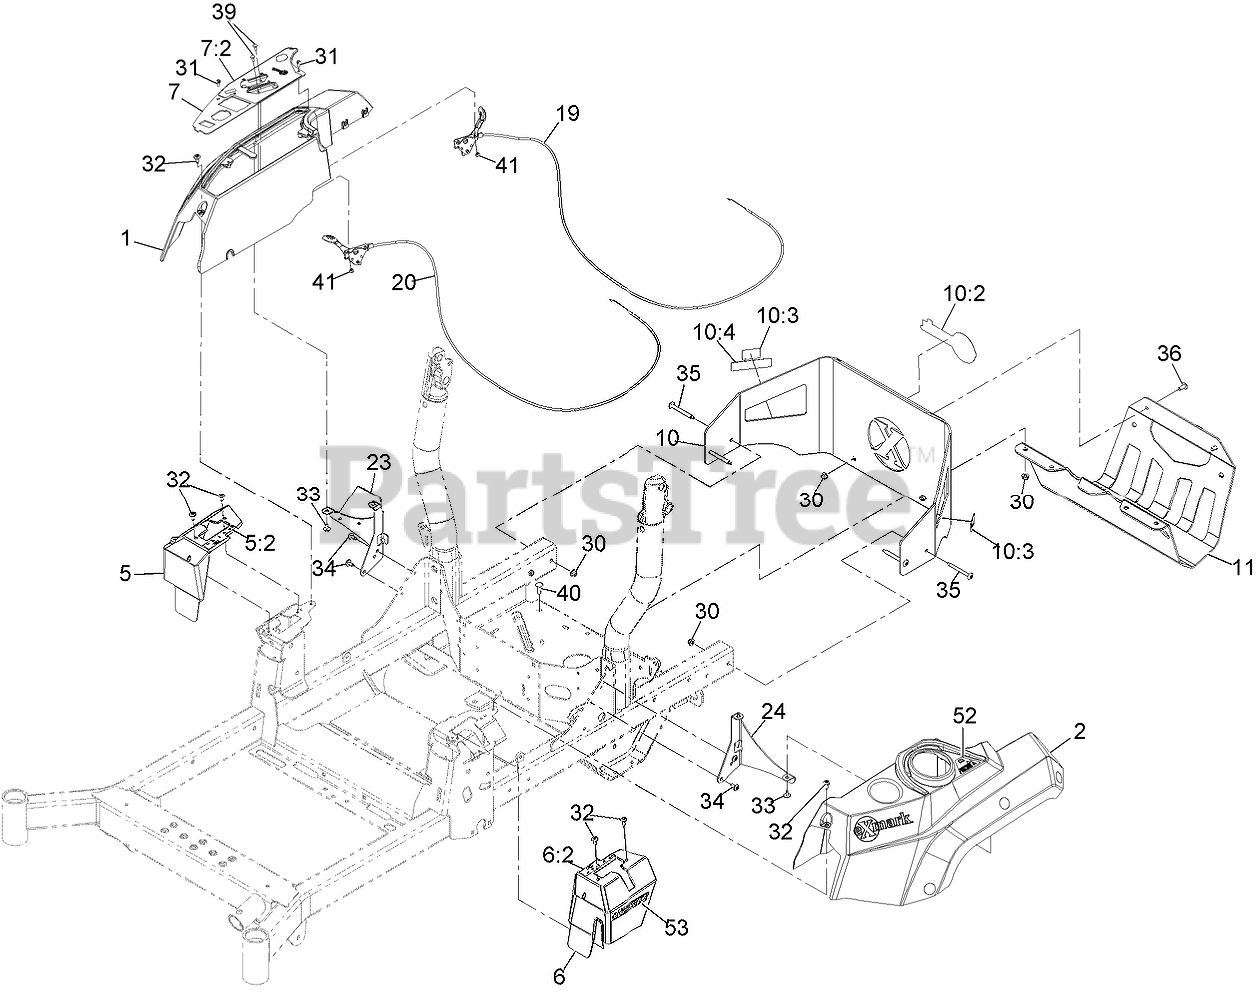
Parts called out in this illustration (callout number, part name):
1	CONSOLE, RH
2	CONSOLE, LH
5	COVER-CONTROL, MOTION (RH
5:2	Decal-Control, Motion (RH)
6	COVER-CONTROL, MOTION (LH
6:2	Decal-Control, Motion (LH)
7	ASM-CONTROL PANEL W/EXMARK DECAL
7:2	DECAL-CONTROL PANEL
10	REAR GUARD ASM W/NOTCH
10:2	DECAL, EXMARK LOGO
10:3	DECAL-WARNING
10:4	DECAL-ARRESTOR, SPARK
11	GUARD-MUFFLER
19	CABLE-CONTROL, CHOKE
20	CABLE-CONTROL, THROTTLE
23	SUPPORT-CONSOLE, RH
24	BRACKET-CONSOLE, LH
30	NUT-HF, NI
31	SCREW-HWH
32	SCREW-SHOULDER
33	SCREW-TORX
34	SCREW-TORX
35	SCREW-TORX
36	SCREW-TORX
39	BOLT-CARR
40	SCREW-CARR
41	NUT-LOCK, NI
52	DECAL-FILL, FUEL
53	DECAL-E-SERIES
